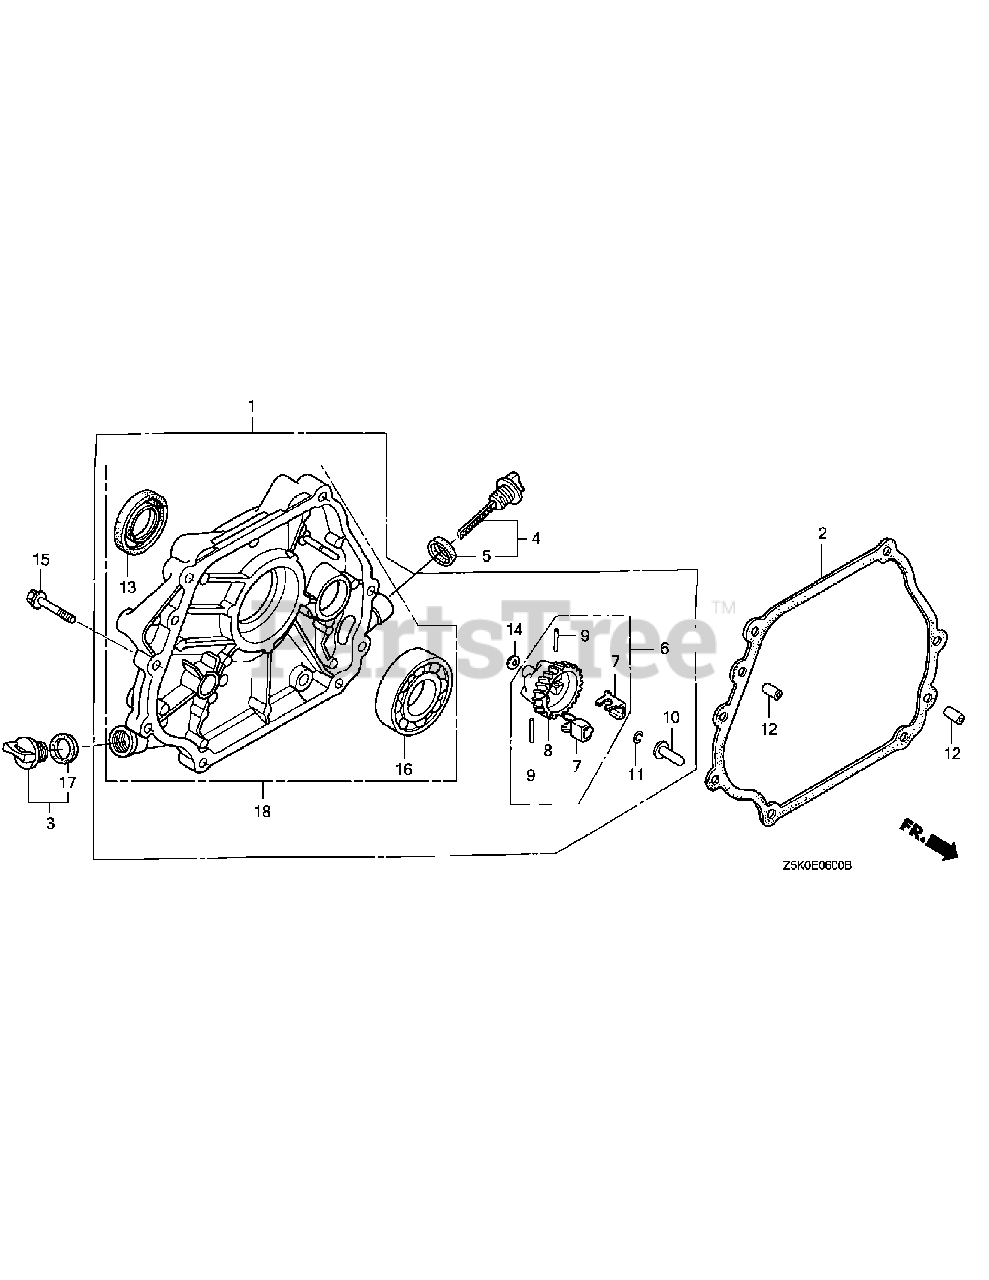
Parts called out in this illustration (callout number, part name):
1	Cover Assy., Crankcase
2	Packing, Case Cover
3	Cap Assy., Oil Filler
4	Cap Assy., Oil Filler
5	Packing, Oil Filler Cap
6	Governor Assy.
7	Weight, Governor
8	Holder, Governor Weight
9	Pin, Governor Weight
10	Slider, Governor
11	Clip, Governor Holder
12	Dowel Pin, 8X12
13	Oil Seal, 30X46X8
14	Washer, Plain, 6Mm
15	Bolt, Flange, 8X35
16	Bearing, Radial Ball, 6206
17	Packing, Oil Filler Cap
18	Cover Assy., Crankcase
